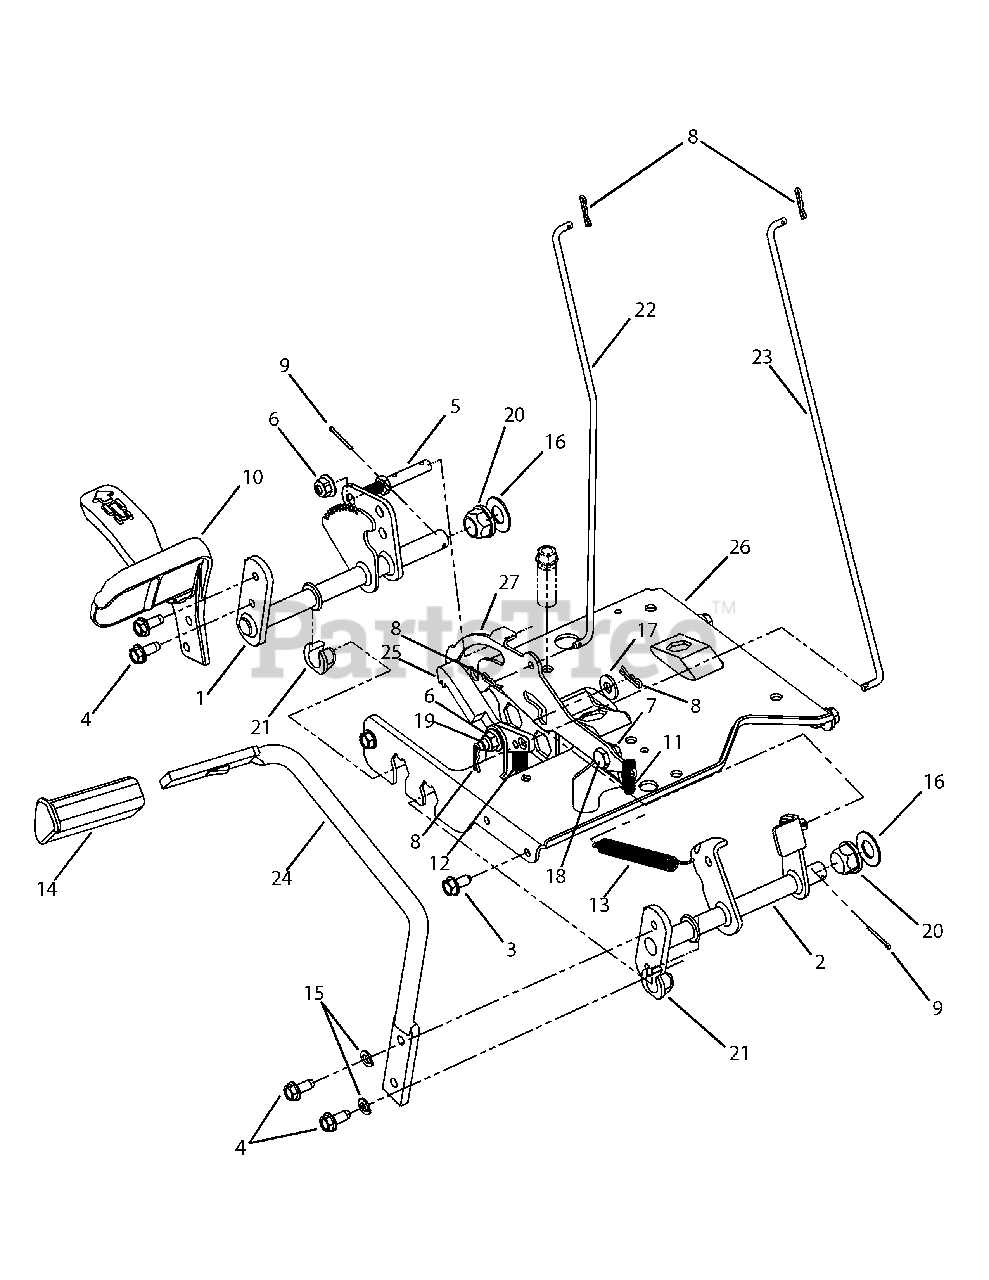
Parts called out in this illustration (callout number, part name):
4	Screw, Self-tapping, 5/16-18, 0.75
5	Pin, 3/8-16, 3/8 x 2.68
6	Nut, Nylon Lock, 3/8-16
7	Nut, Flange Lock, 5/16-18, Gr5
8	Pin, Cotter, .072 Dia. x 1.13 Lg
9	Pin, Cotter, 3/32, 1.0
11	Spring, Compression, .405 x 1.17
12	Spring, Extension, .50 OD x 1.41 Lg
13	Spring, Extension, .50 Dia x 6.37 Lg
14	Pad, Brake, Control
15	Washer, Lock, 5/16
16	Washer, Flat .64 x 1.24 x .06
17	Washer, Flat, .385 x .870 x .092
18	Shoulder, Screw .437
19	Shoulder, Screw 3/8-16
20	Bearing, Hex Flange
21	Bearing, Hex Flange, .628 ID, Split
22	Rod, Control, Brake Lock
23	Rod, Control, Cruise
27	Bracket, Lockout, Hydro
